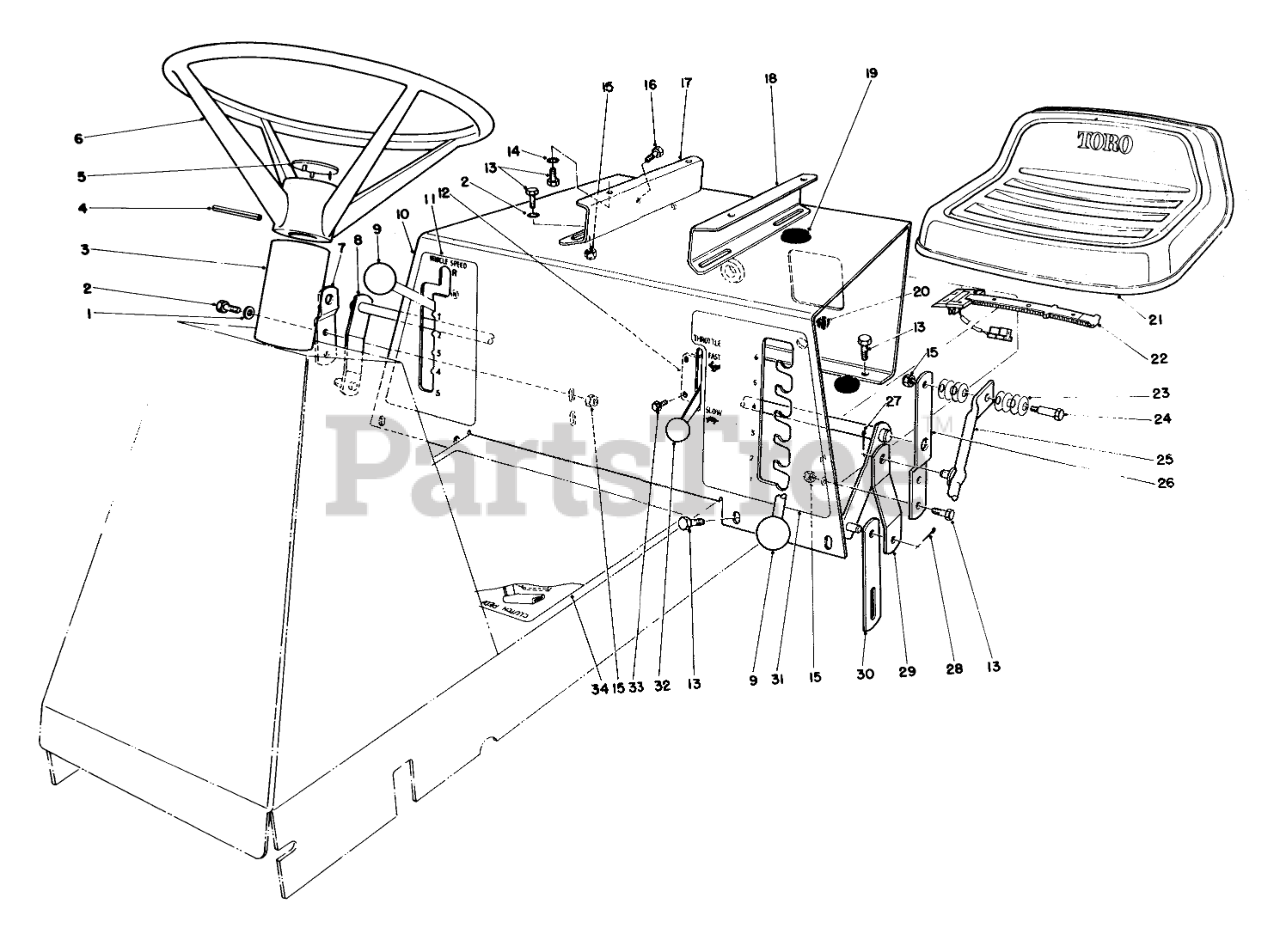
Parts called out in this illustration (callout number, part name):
1	WASHER-PLAIN
2	SCREW-HH
3	STRG. SHAFT COVER
4	PIN-ROLL
5	Cap-Steering Wheel
6	Wheel-Steering (Incl. Ref. #5)
7	Bracket H.O.C Support
8	HOC LEVER WA B
10	Support Seat
11	Decal-Transmission
12	Throttle Control (Incl. Ref. #32)
13	SCREW-HH
14	WASHER-LOCK
15	NUT-LOCK, NI
16	SCREW-HH
17	Bracket-Seat LH.
18	Bracket-Seat RH.
19	GROMMET
20	GROMMET
21	Seat
22	SWITCH-SEAT
23	WASHER-BELLEVILLE
24	BOLT-SHOULDER
25	HOC LEVER WA B
26	Bracket
27	PIN-COTTER
28	PIN-COTTER
29	Bracket-Height Of Cut Engagement
30	Link-Deck Suspension
31	Decal-Height Of Cut
32	KNOB-CONTROL
33	SCREW-HWHTF
34	Decal-Instructions
